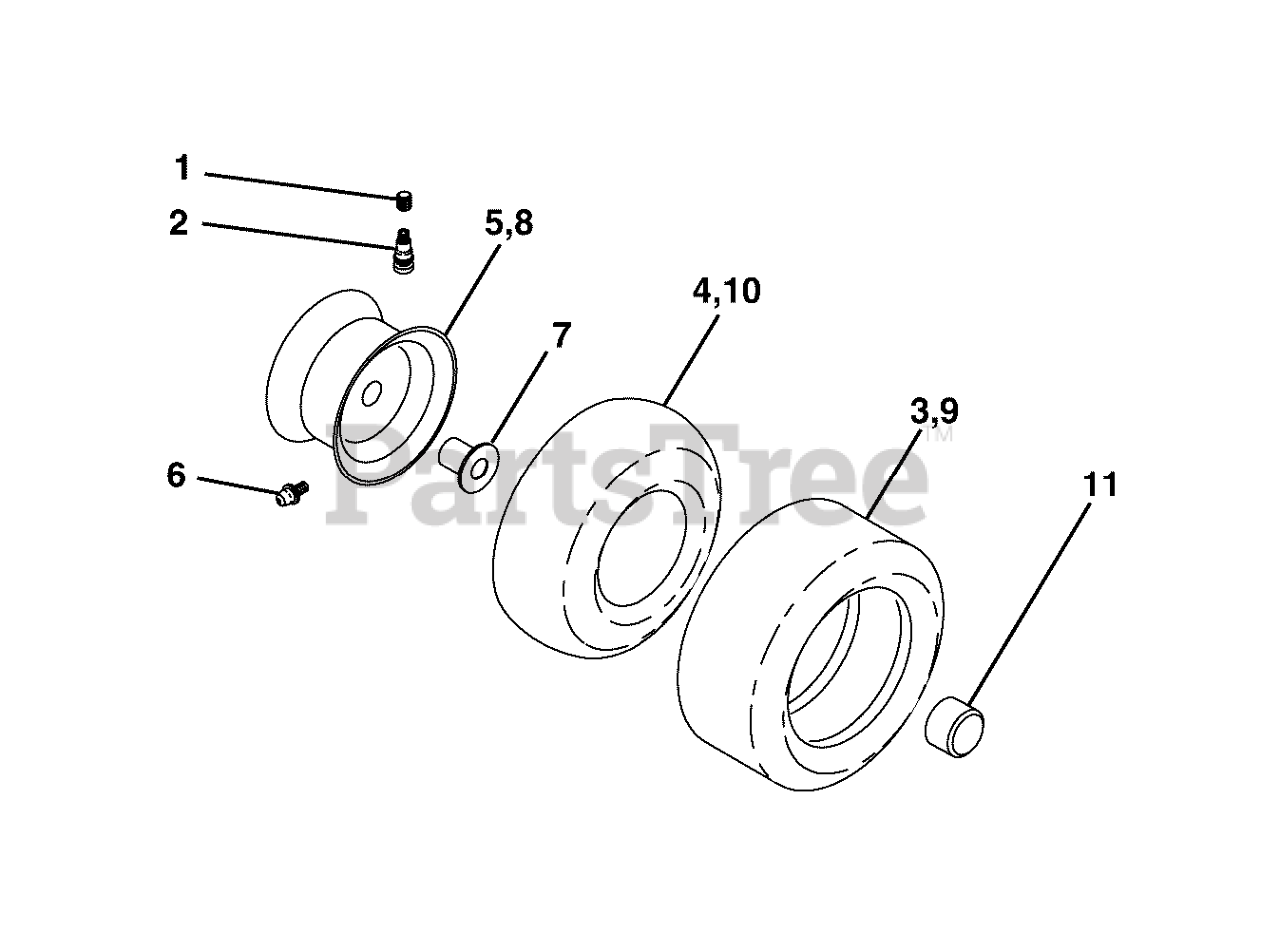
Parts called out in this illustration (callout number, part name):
1	CAP, Valve, Tire
2	STEM, Valve
3	RIM ASSEMBLY, Front
4	TUBE, Front
5	TIRE, Front, 15 x 6-6
6	FITTING, Grease
7	BEARING, Flange
8	CAP, Axle (Front Wheel Only)
9	TIRE, Rear, 20 x 8-8
10	TUBE, Rear
11	RIM ASSEMBLY, Rear
